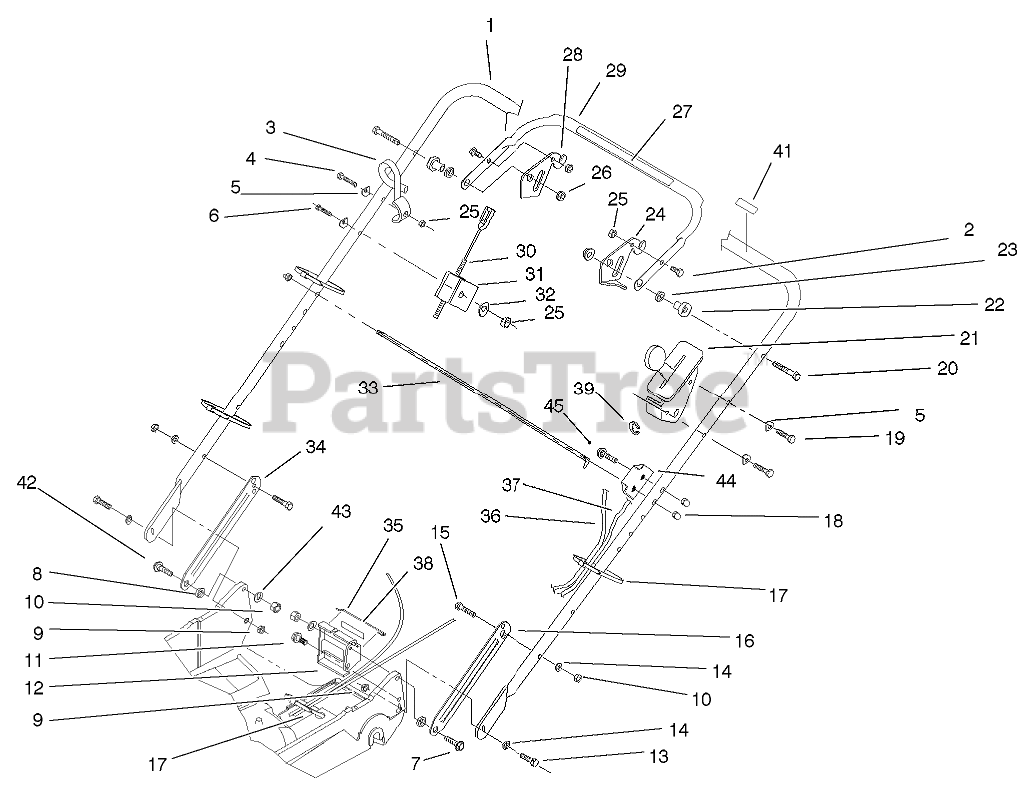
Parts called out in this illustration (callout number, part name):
2	SCREW-HH
3	GUIDE-ROPE
4	SCREW-HH
5	WASHER
6	SCREW-HH
7	SCREW-SHOULDER
8	SPACER
9	NUT-LOCK, NI
10	NUT-LOCK, NI
11	SCREW-HWHTF
12	BRACKET-ADJUSTMENT, TRACTION
13	SCREW-HH
14	WASHER-BELLEVILLE
15	SCREW-HH
16	LATCH-HANDLE, LH
17	TIE-CABLE
18	NUT-CAP
19	SCREW-HH
20	SCREW-HH
21	BRACKET-CONTROL, THROTTLE
22	SPACER-SUPPORT
23	SPACER-NYLON
24	LEVER-CONTROL
25	NUT-LOCK, NI
26	NUT-LOCK, NI
27	DECAL/TRACTION CONTROL
28	LEVER-CONTROL
29	BAR-CONTROL
30	CABLE-BRAKE
31	SUPPORT-CABLE
32	WASHER-FLAT
33	ROD-SUPPORT, BAG
34	LATCH-HANDLE, RH
35	RETAINER-CABLE
36	CABLE-TRACTION
37	CABLE-THROTTLE
38	DECAL-POSITION, GEAR
39	E-RING
41	DECAL-PROTECTION, EAR
42	SCREW-SHOULDER
43	WASHER-PLAIN
44	PLATE-ALIGNING, BAG
45	SCREW-CARR
